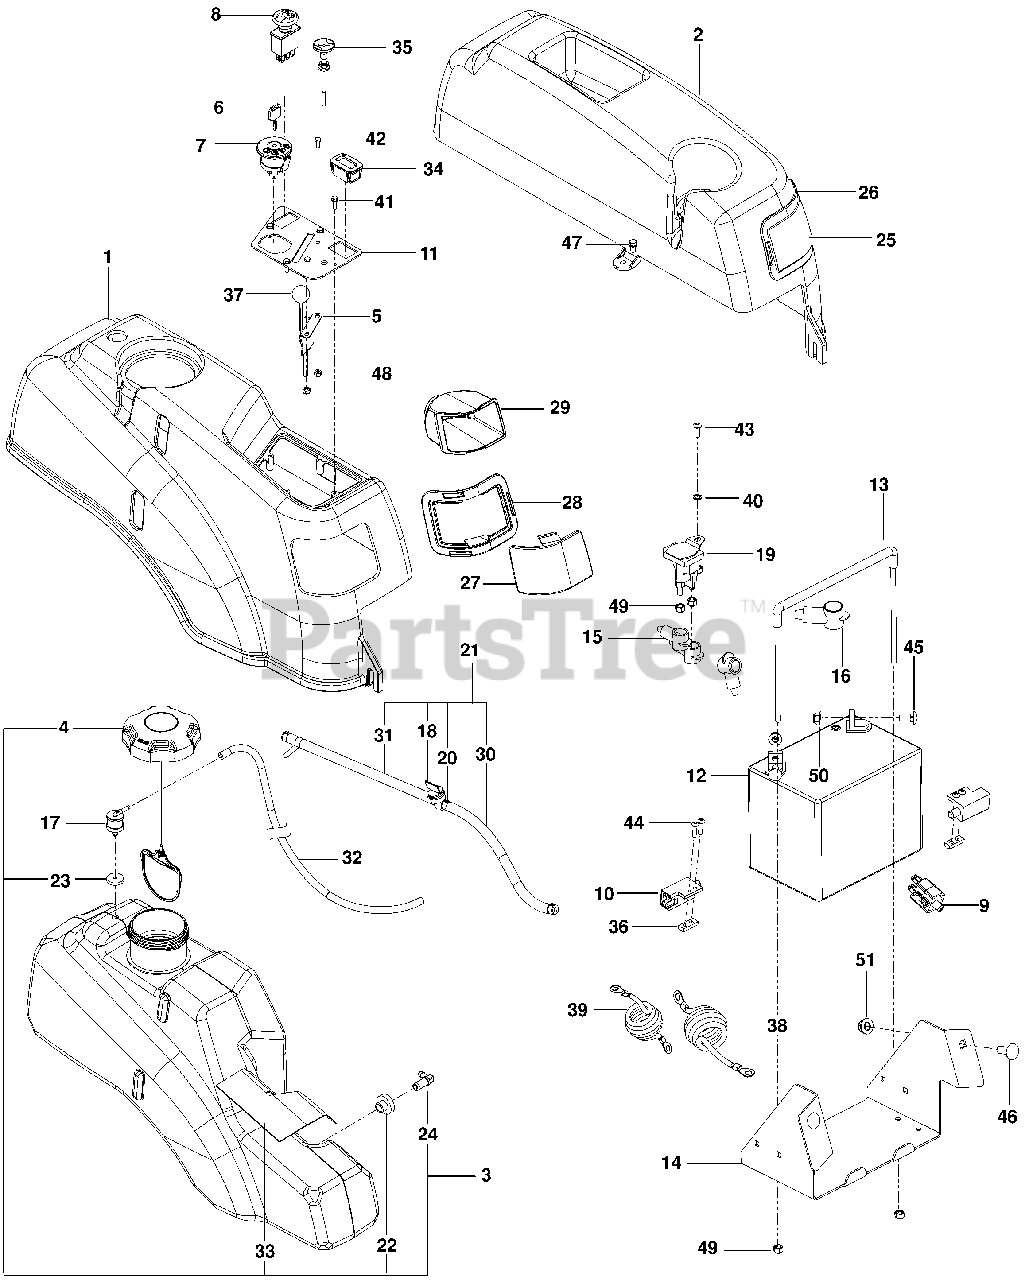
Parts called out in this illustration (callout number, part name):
1	FENDER RT, BLACK
2	FENDER, LT, BLK
3	FUEL TANK ASM, LARGE
4	CAP, FUEL
5	THROTTLE CABLE
7	IGNITION SWITCH
9	SWITCH, BRAKE 3P
13	BATTERY TIE DOWN ASSEMBLY
14	BOX, BATTERY, BLACK
15	TERMINAL COVER-SM
16	INSULATOR
17	VALVE.FUEL.CHECK
18	FUEL VALVE
19	SOLENOID.W/BRASS.PLUNG
20	HOSE CLAMP
22	RUBBER GROMMET
23	GROMMET, CHECK VALVE
30	GAS LINE 10"
31	FUEL LINE 14"
32	HOSE, VAPOR 3/16 X 48"
35	CHOKE CABLE
37	KNOB ROUND BALL
38	CABLE POSITIVE, LONG
39	BATTERY CABLE, NEGATIVE
40	WASHER 1/4 INT TOOTH
41	SCR #10-12X3/4 HEX WAS HD ZD
42	HCS #10-24 X 1/2
43	SCR 1/4-20 X 5/8 BTN SKT HD ZD
44	SCR #10-24 X .75 SKT HD BLK
45	BOLT 5/16C X 3/4" CARRIAGE
46	RHSNB 3/8C X 1
47	BOLT 1/4-20 X 1/2 HWST
48	NUT 10-24 NYLOC
49	NUT 1/4-20 NYLOC
50	5/16-18 NYLOC FLANGE NUT
51	NUT 3/8-16 HEX FLG NYLOC ZD
